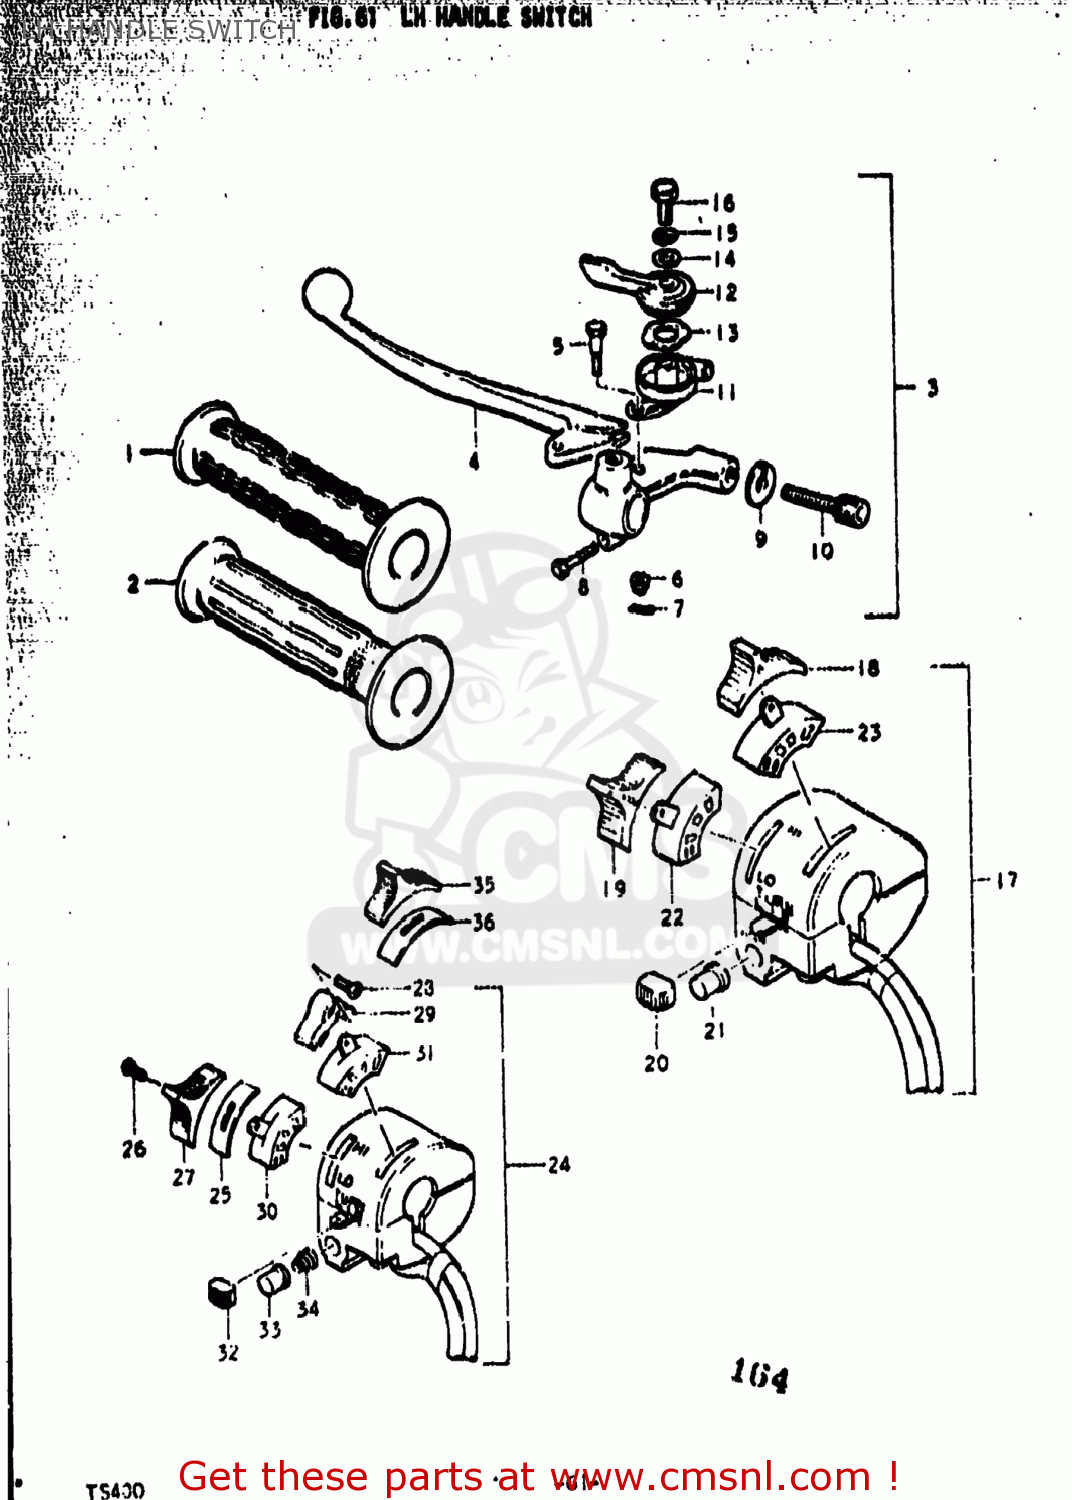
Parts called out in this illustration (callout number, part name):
1	GRIP
2	GRIP,L
3	LEVER ASSEMBLY
4	LEVER,CLUTCH
5	BOLT,LEVER
6	NUT,LEVER FITTNG
7	COTTER PIN
8	BOLT
9	NUT,CABLE ADJUSTER
10	ADJUSTER,CABLE
11	LEVER ASSEMBLY
12	LEVER
13	WASHER,ADJUSTER
14	WASHER,STARTER LEVER
15	LOCK WASHER
16	BOLT
17	SWITCH ASSEMBLY,HANDLE
18	KNOB,HANDLE SWITCH
19	KNOB,HANDLE SWITCH,UPPER
20	KNOB,HANDLE SWITCH
21	BUTTON, HORN
22	SLIDING BLOCK, DIMMER SWITCH
24	SWITCH ASSEMBLY,HANDLE,LEFT
25	PLATE,DIMMER KNOB
26	SCREW, DIMMER
27	KNOB,HANDLE SWITCH,UPPER
28	SCREW
29	KNOB
30	SLIDING BLOCK, DIMMER SWITCH
32	KNOB,HANDLE SWITCH
33	BUTTON, HORN
34	SPRING,BUTTON
35	KNOB,HANDLE SWITCH
36	PLATE,LIGHTING KNOB
